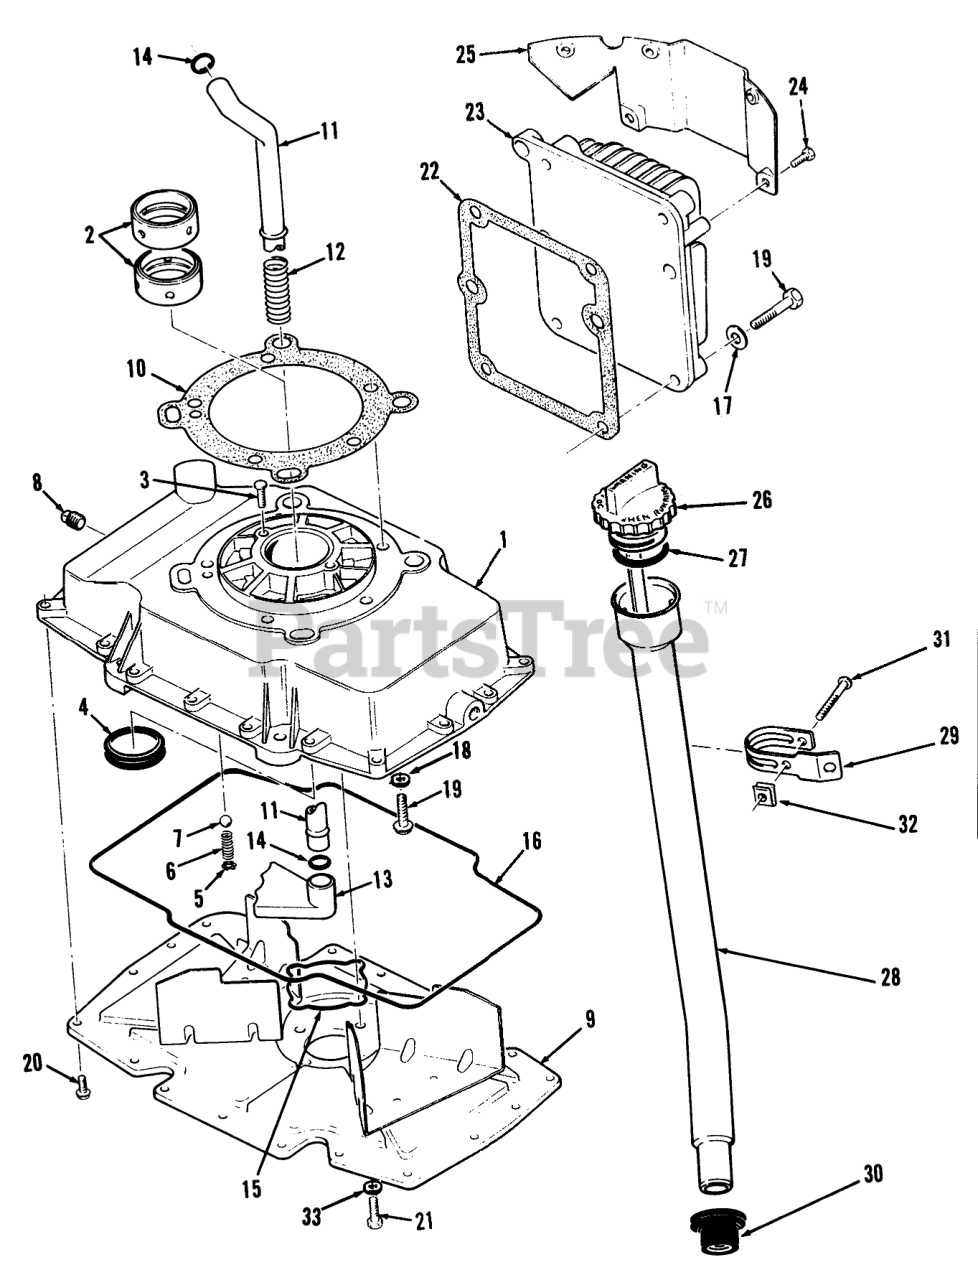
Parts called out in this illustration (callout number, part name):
1	Oil Base (Includes Items 2 thru 7)
2	Rear Crankshaft Bearing-STD
3	Screw
4	OIL-SEAL
5	RETAINING-RING
6	Spring
7	BALL-BEARING
8	Plug
9	OIL-BASE COVER ZINC
10	OIL-BASE GASKET
11	OIL-PICKUP TUBE
12	OIL-PICKUP SPRING
13	OIL-PICKUP CUP
14	O-RING
15	OIL-SEAL
16	OIL-SEAL
17	Washer
18	Washer
19	HEX-HEAD CAP SCREW
20	Bolt
21	Screw
22	Gasket
23	OIL-COOLER
24	Bolt
25	OIL-COOLER BAFFLE
26	OIL-LEVEL INDICATOR
27	O-Ring
28	OIL-FILL TUBE (ZINC)
29	SUPPORT-BRKT (ZINC)
30	Seal
31	Screw
32	Nut
33	Washer
